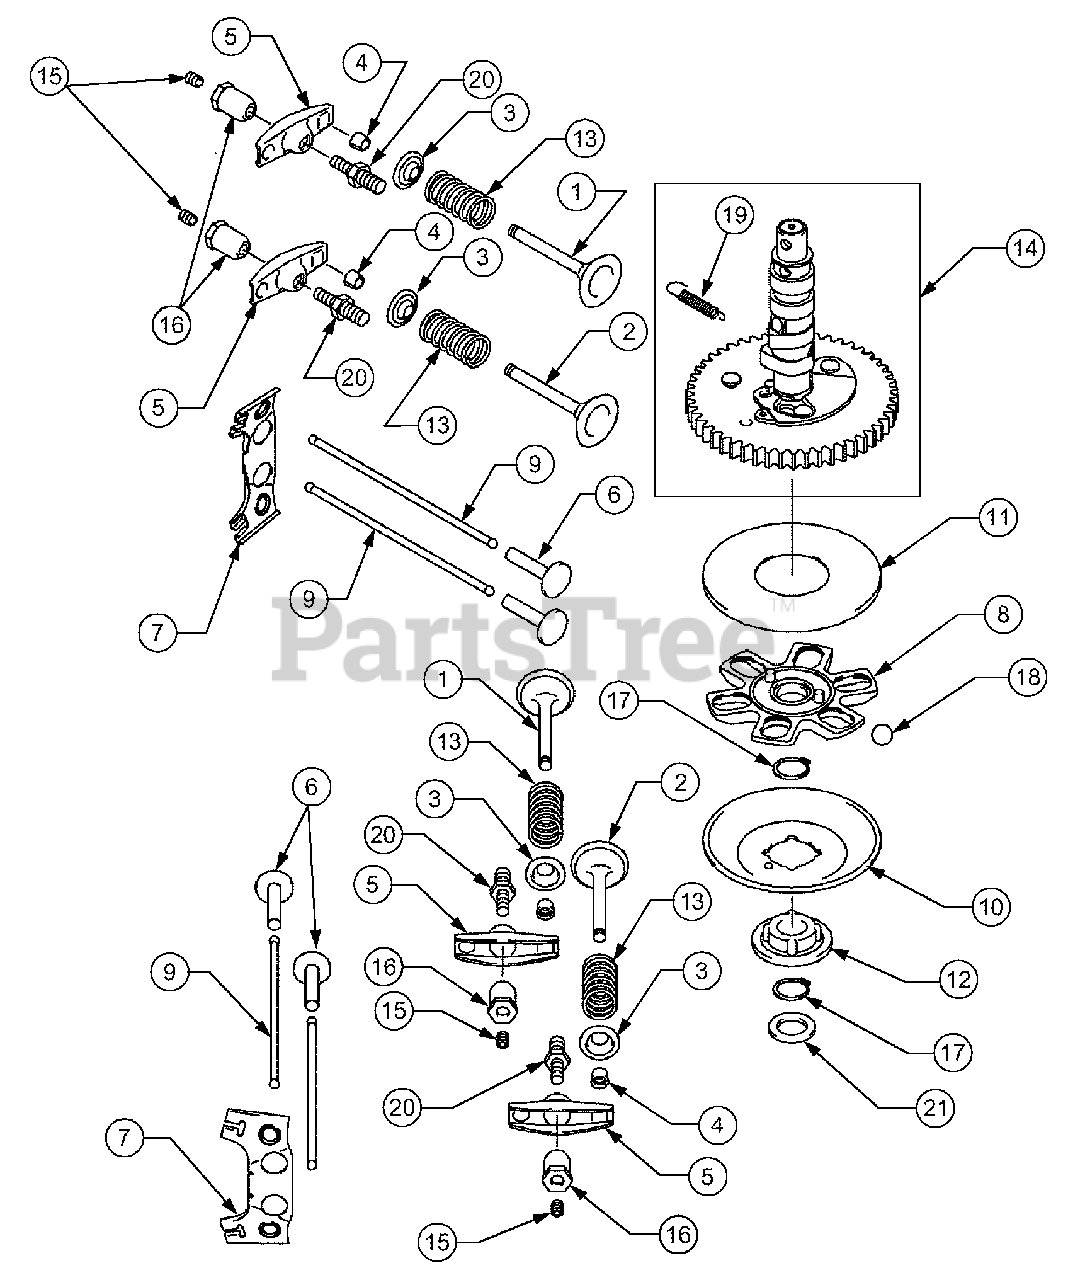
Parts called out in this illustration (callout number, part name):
1	Valve, Intake
2	Valve, Exhaust
3	Retainer, Valve Spring
5	Arm, Rocker
12	Sleeve
13	Spring, Engine Valve
14	Camshaft, Comp
17	Ring, Snap
18	Ball
19	Spring
20	Bolt
